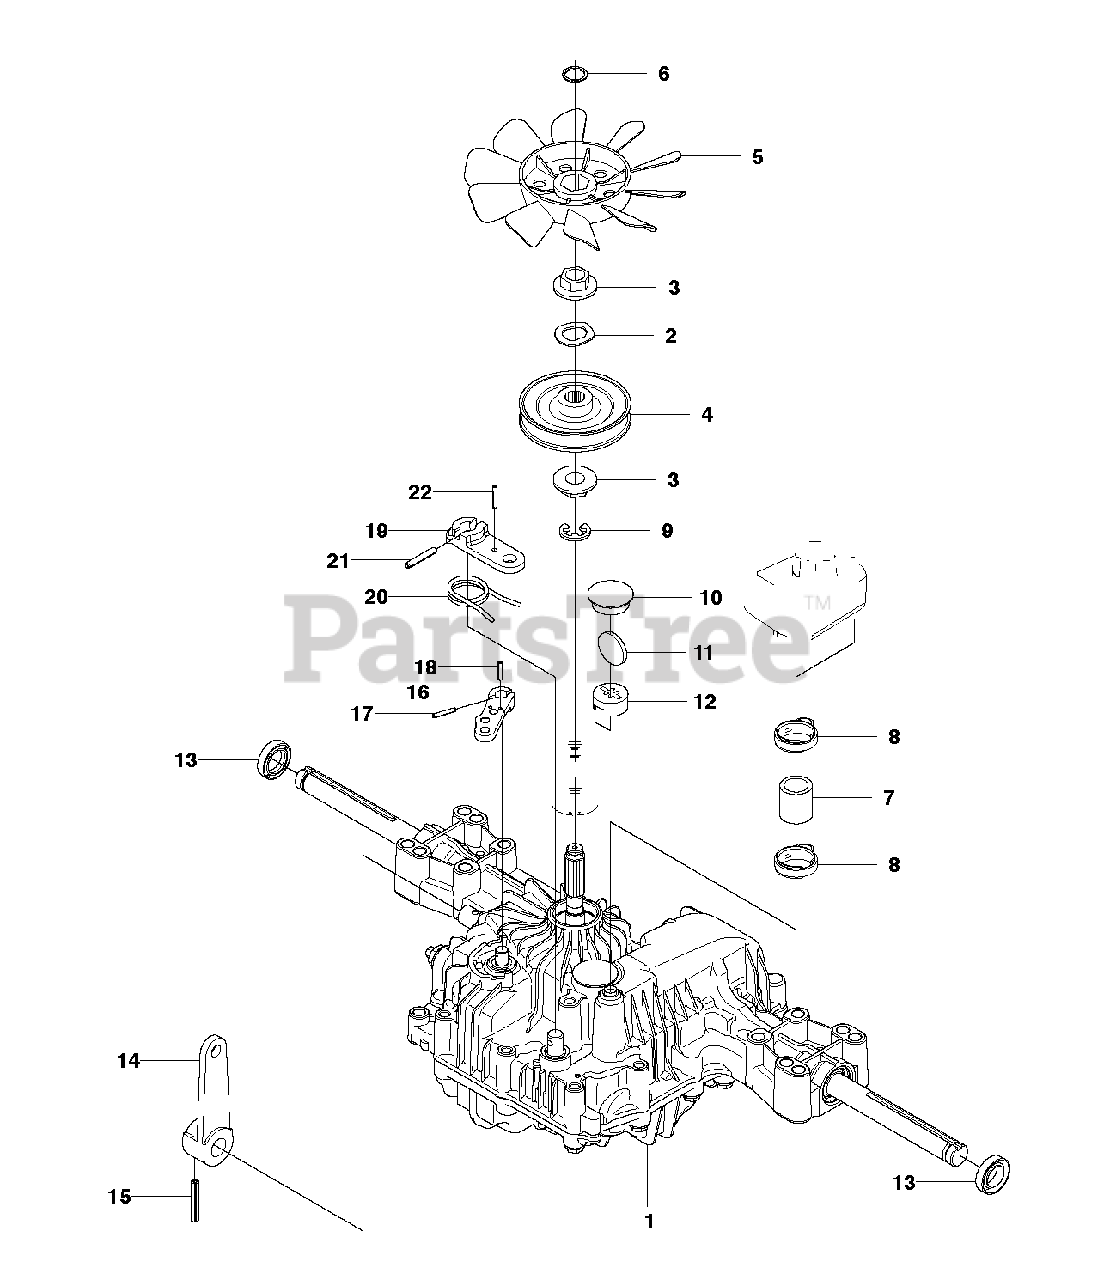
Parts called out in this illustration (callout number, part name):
1	HYDROSTAT
2	WASHER **
5	FAN
6	RETAINING RING **
8	CLAMP
9	CLIP
10	PLUG
11	MAGNET
12	MAGNET HOLDER
13	SEALING
14	CONTROL LEVER
15	PIN
16	ARM
17	PIN
18	PIN
19	ARM
20	RETURN SPRING
21	PIN
22	PIN
